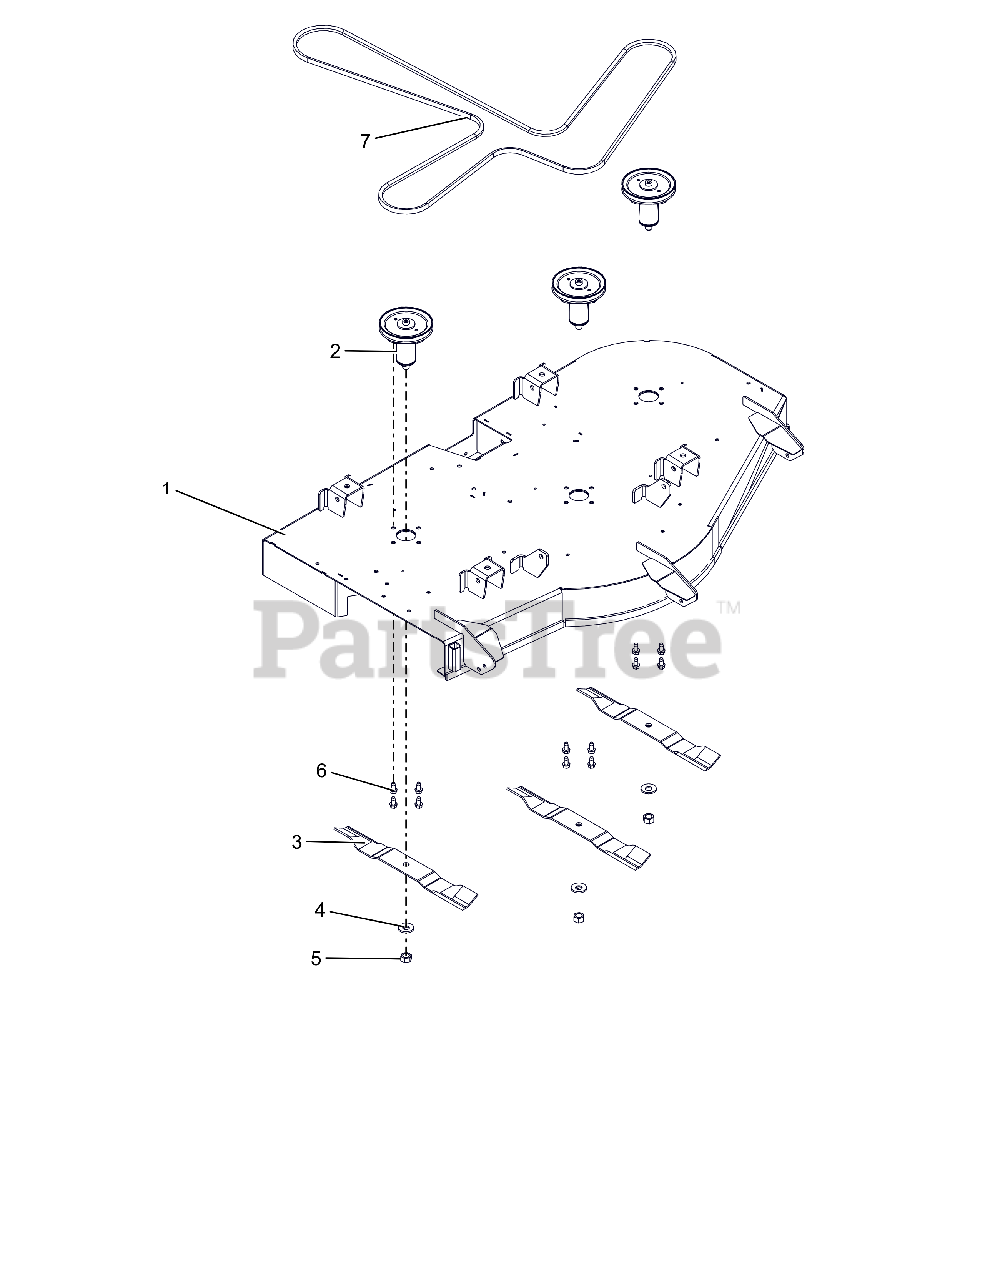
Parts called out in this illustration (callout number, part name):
1	KIT, 52" ARIENS DECK W/DECALS
2	ASSY, SPINDLE 52" (ORANGE)
3	BLADE, 18" - 30 DEG .5 OFFSET
4	WSHR-BLVL .669X1.535X.138
5	NUT-HEX .62-18 YWZC
6	@SCR-TAP .38-16X.75 HWH TR YWZ
7	V-BELT, HA-WRAPPED
